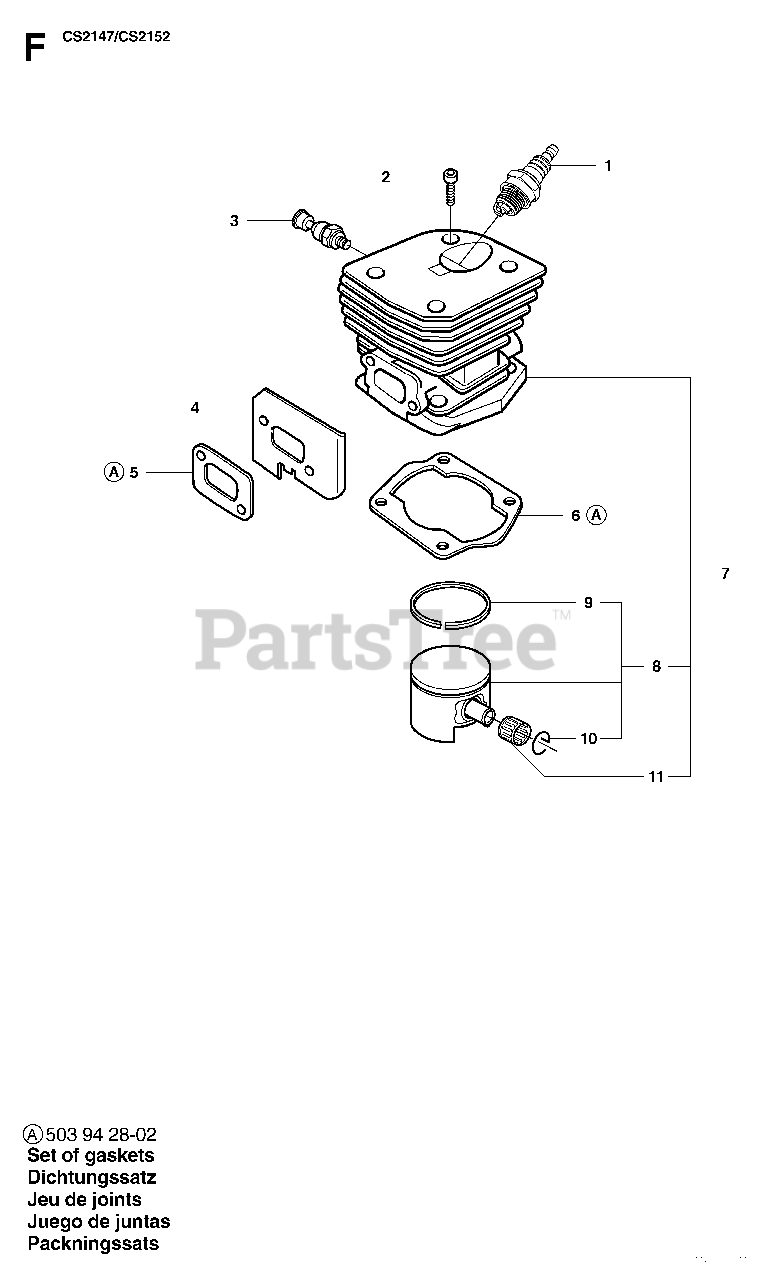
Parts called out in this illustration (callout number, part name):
1	SPARK PLUG RCJ7Y
2	SCREW MC6S 5X25
3	DECOMPRESSION VALVE
7	PISTON CYLINDER KIT 353
8	PISTON
8	PISTON ASSY
9	%PISTON RING
9	PISTON RING
10	LOCKING RING
11	RP SUPPORT BUSHING
A	GASKET SET
